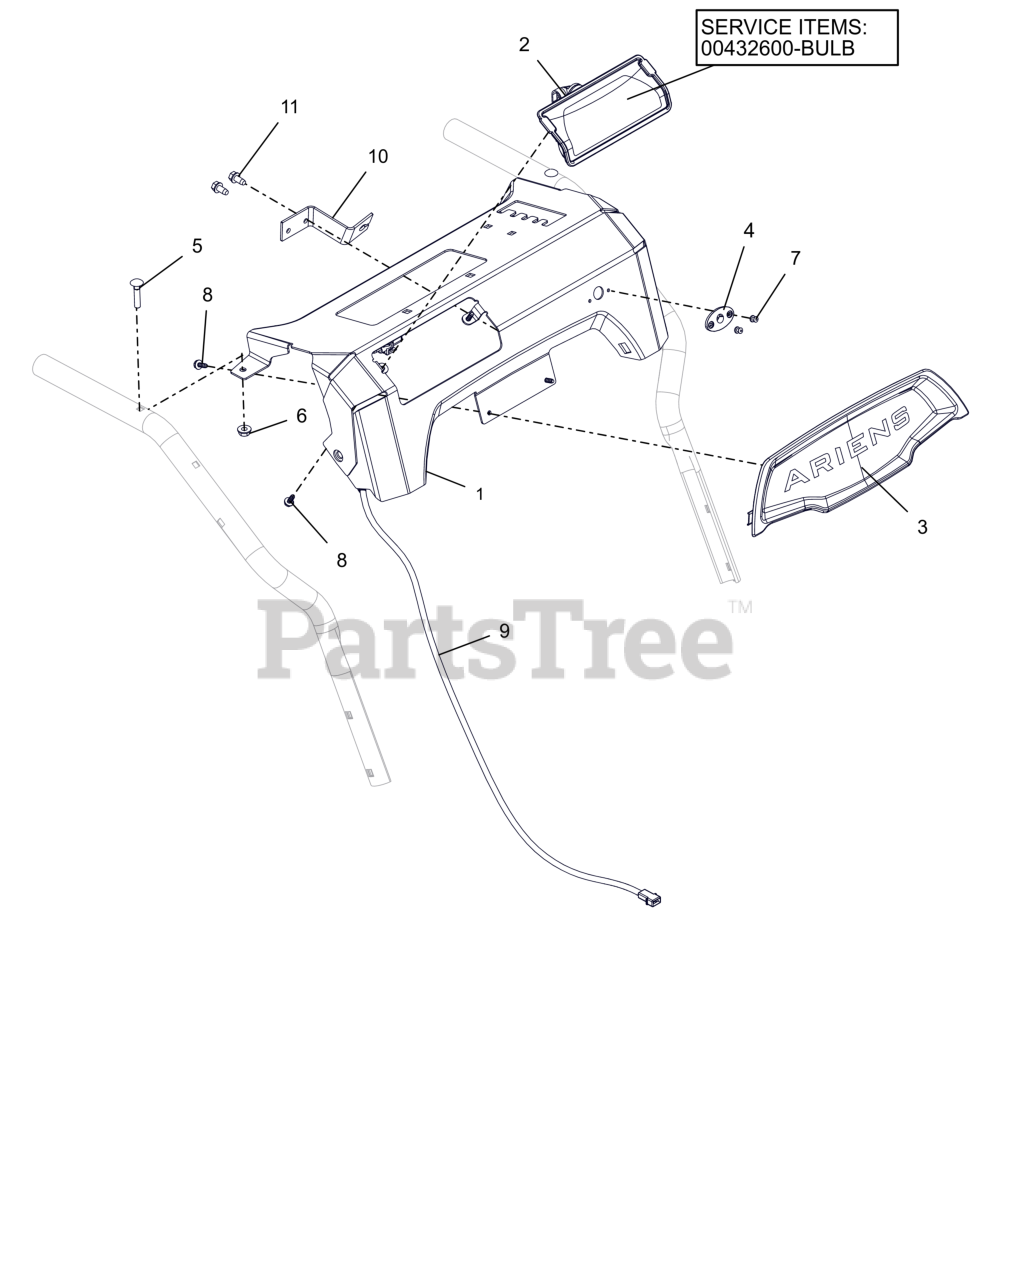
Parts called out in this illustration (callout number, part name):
1	CTRL PANEL W/DECAL-SM DASH DLX
2	HEADLIGHT ASY, HALO 20W 2SHOT
2	BULB, LIGHT-HALOGEN 20W
3	BEZEL, DASH - ARIENS SM DASH
4	BSHG, CHUTE CRANK
5	BLT-RDHDXLSQNK.25-20X1.25 G5ZC
6	NUT-LK-TOP-FLG .250-20 GF ZCC
7	RVT-POP #43 .125X.313 STL ZINC
8	SCR, PLASTIC #10X.50
9	HARNESS, LIGHT - COMPACT
10	ANCHOR, DEFLECTOR CABLE
11	SCR-TAP .25-20X.50 HWH ZCC
